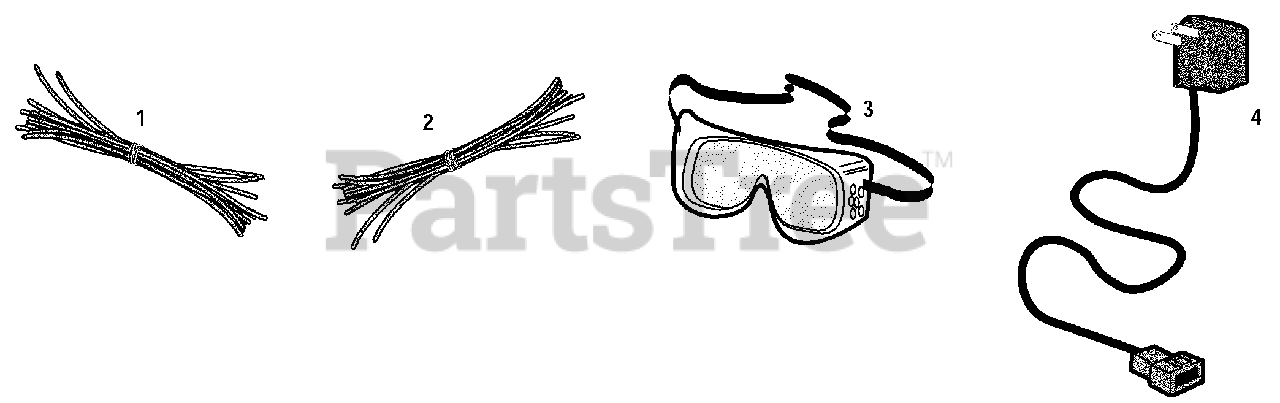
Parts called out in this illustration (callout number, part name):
1	Trimmer String Kit, .155"
2	Trimmer String Kit, .130"
3	Safety Goggles
4	Battery Charger (Electric Start Model)
